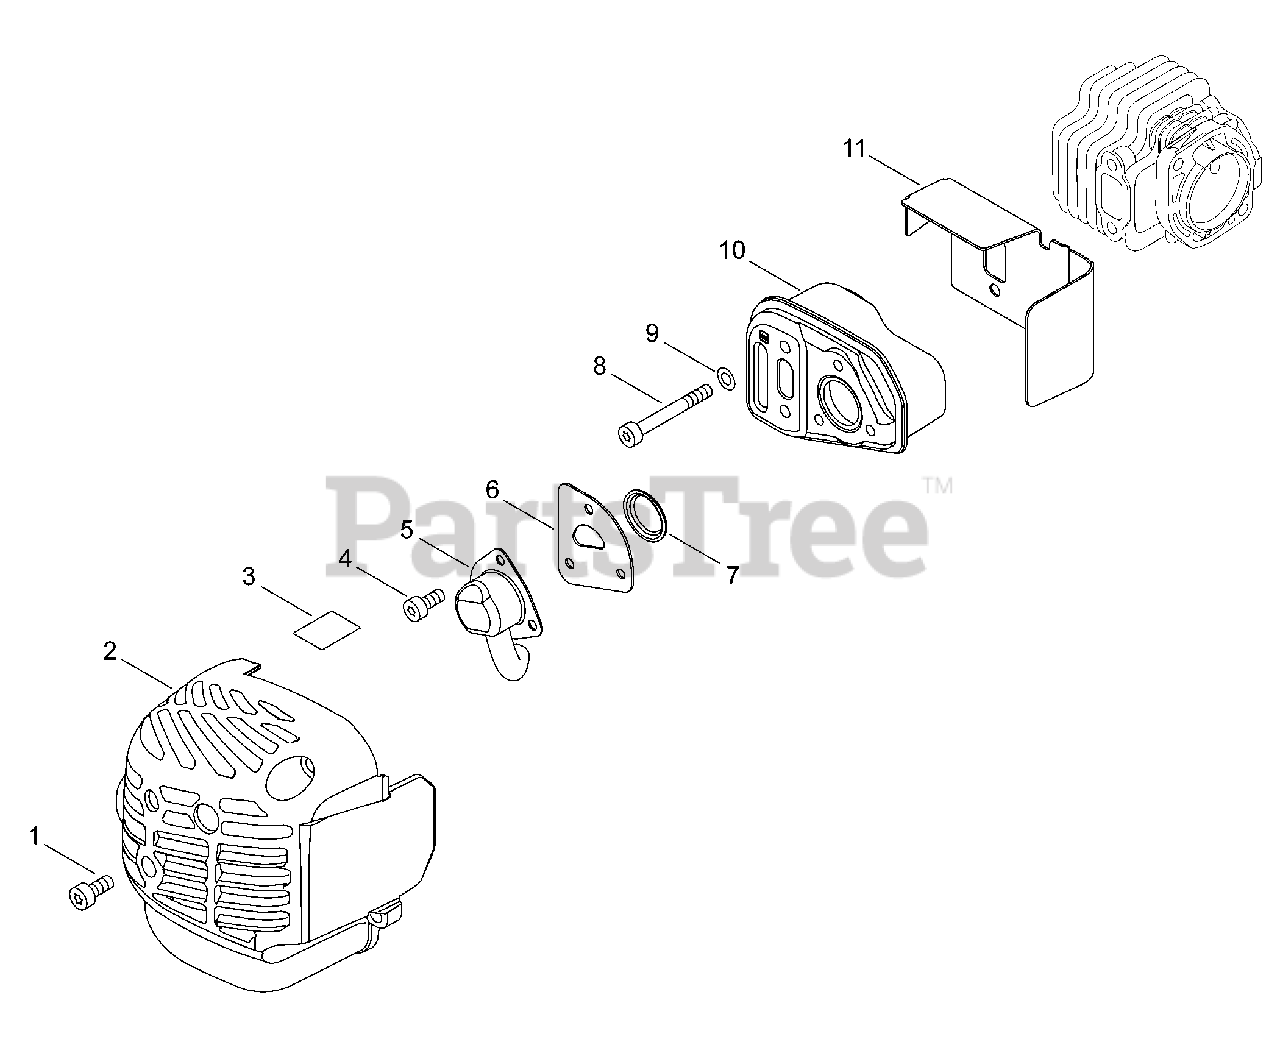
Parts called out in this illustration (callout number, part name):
1	BOLT, TORX 5
2	COVER,MUFFLER
3	LABEL,CAUTION
4	BOLT, TORX 4
5	GUIDE, EXHAUST
6	GASKET,EXHAUST
7	SCREEN, ARRESTOR
8	BOLT, TORX 5
9	WASHER 5
10	MUFFLER
11	GASKET,EXHAUST
